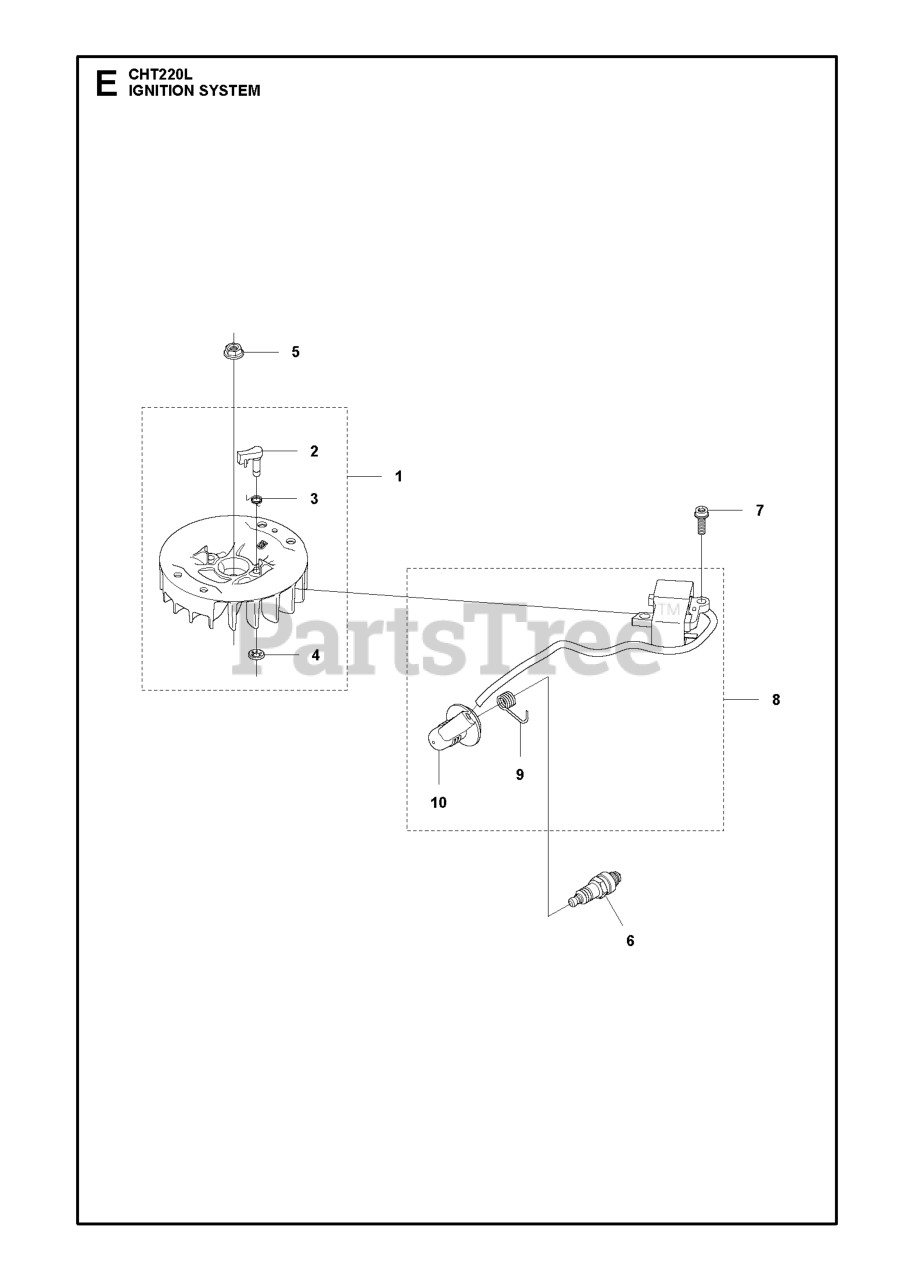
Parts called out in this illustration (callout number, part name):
1	FLYWHEEL
2	STARTER PAWL
4	LOCK WASHER
5	FLANGE NUT
6	SPARK PLUG RESISTOR NGK CMR6A
8	IGNITION MODULE
9	SPRING
10	CAP SPARK PLUG
